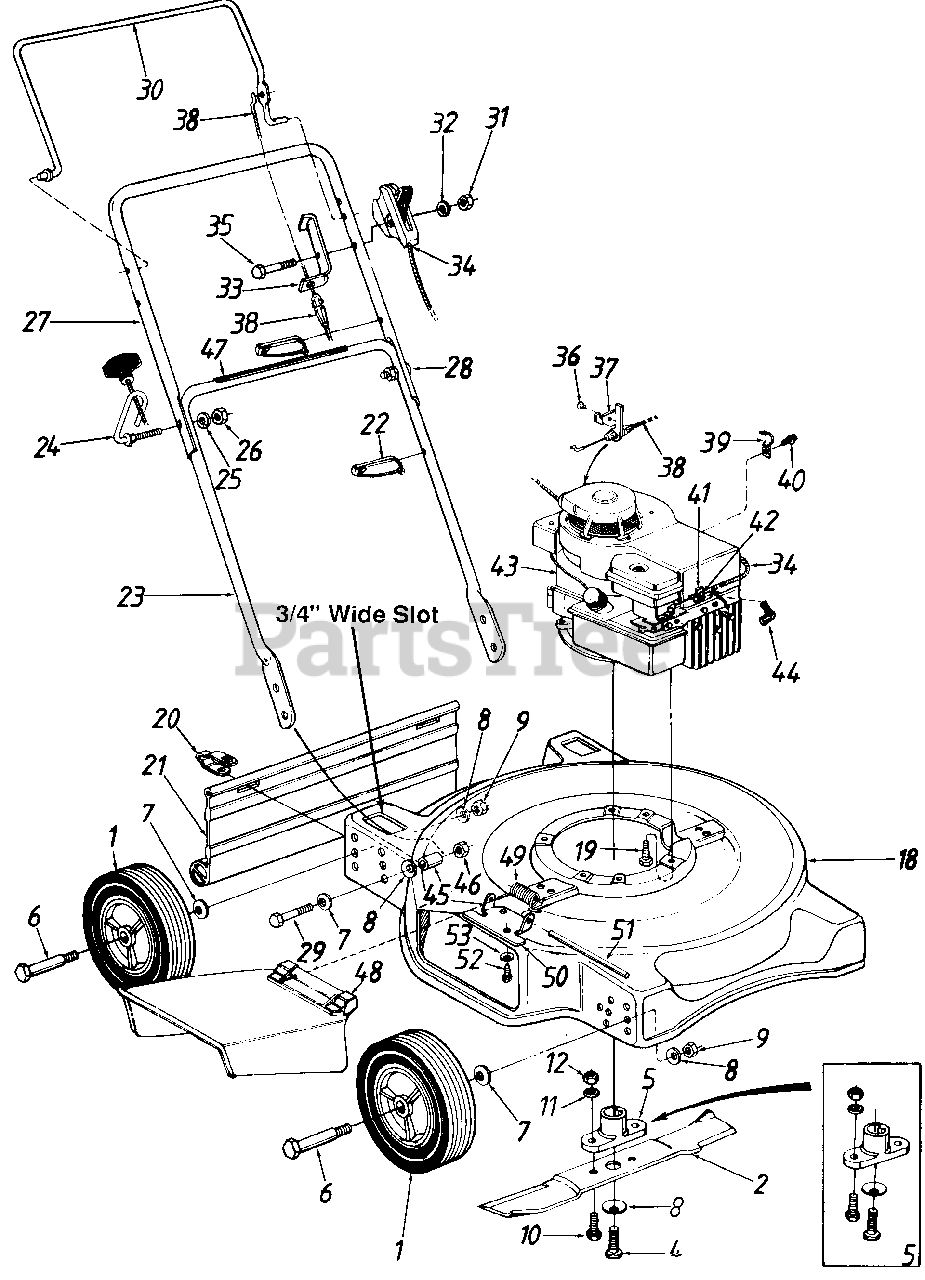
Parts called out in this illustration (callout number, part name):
1	Wheel Ass'y. Complete
2	20" Blade
4	Hex Bolt 3/8-24 x 1.5" Lg.
5	Blade Adapter Kit (Keyed)
6	Axle Bolt
7	Bell-Wash. .380" I.D. x .88"
8	Bell-Wash. .39" I.D. x 1.13"
9	Hex Nut 3/8-16 Thd.
10	Hex Bolt 3/8-24 x 1" Lg.
11	L-Wash. 3/8" I.D.
12	Hex Nut 3/8-24 Thd.
18	20" Deck Ass'y.
19	Hex Wash. Hd. Scr. 3/8-16 x 1" Lg.
20	Hinge Clip
21	Rear Flap 16.75" Lg.
22	Cable Tie
23	Lower Handle
24	Rope Guide Bolt
25	L-Wash. 5/16" I.D.
26	Hex Nut 5/16-18 Thd.
27	Upper Handle
28	Curved Carriage Bolt 5/16-18 x 1.38" Lg.
29	Hex Bolt 3/8-24 x 1.5" Lg.
30	Control Handle
31	Hex Nut 1/4-20 Thd.*
32	Spr. Wash. .265" I.D. x .562"
33	Cable Mounting Bracket
34	Throttle Control Ass'y. Comp.
35	Hex Bolt 1/4-20 x 1.75" Lg.*
36	Pop Rivet
37	Cable Bracket
38	Control Cable-36"
39	Casing Clamp
40	Hex B-Tap Scr. #10 x .38" Lg.
41	Casing Clamp
42	Hex Wash. Hd. AB-Tap Scr. #8 x .50" Lg.
43	Engine
44	Spark Plug Boot
45	Spacer .381" I.D. x .56" O.D. x.75" Lg.
46	Hex L-Nut 3/8-24 Thd.
47	Instruction Label-Handle
48	Chute Deflector Ass'y.
49	Torsion Spring
50	Adapter Plate
51	Hinge Pin
52	Hex Self-Tap Scr. 1/4-20 x .5"
53	Bell-Wash. 1/4" I.D.
